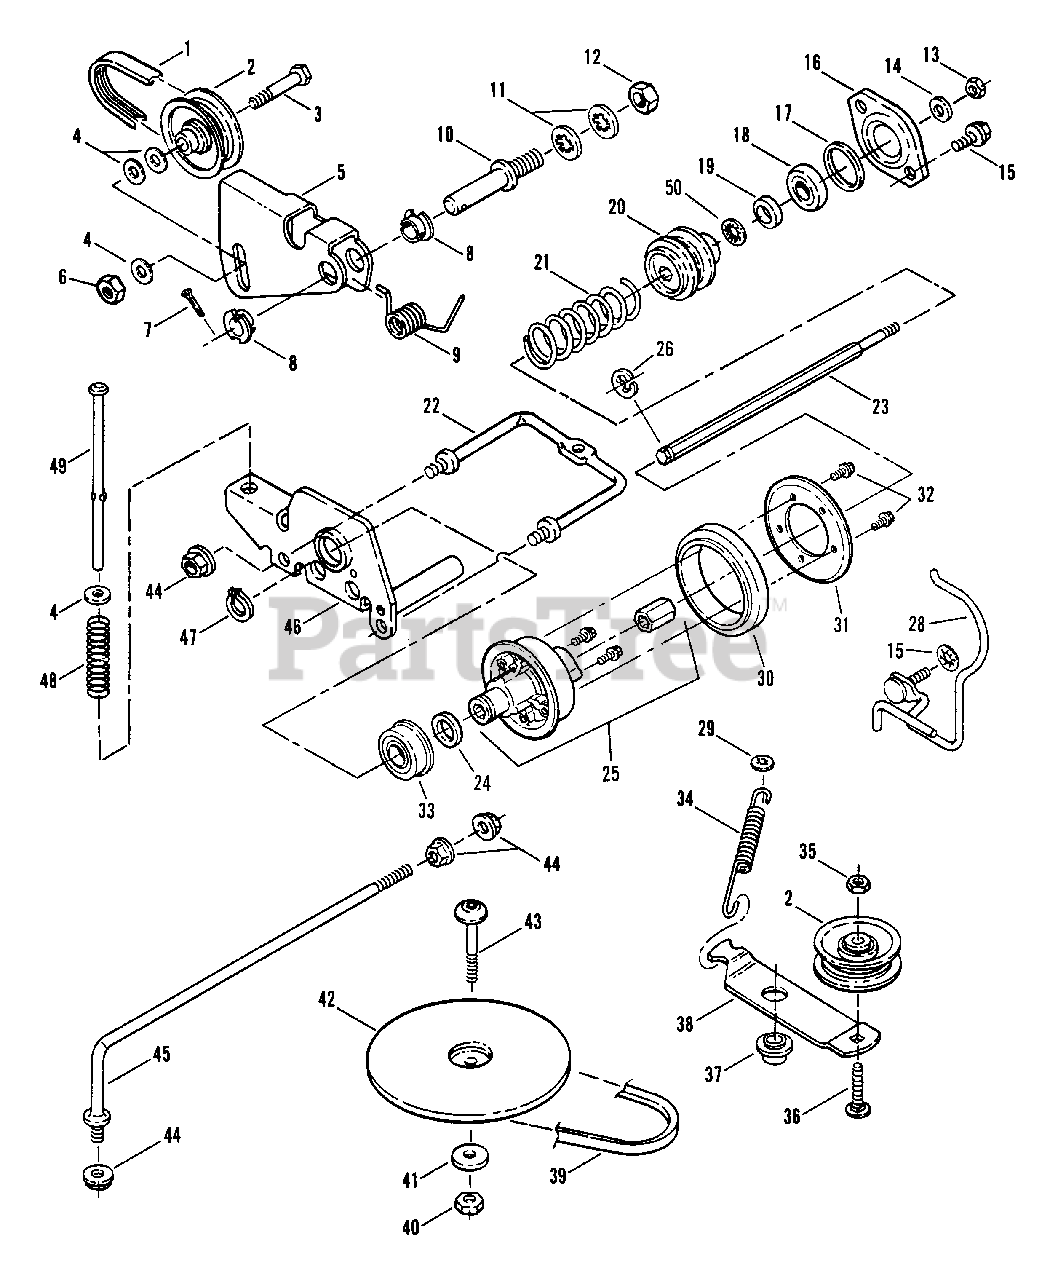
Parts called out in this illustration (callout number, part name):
1	BELT, Poly-V
2	PULLEY, Idler
3	SCREW, 1/4-28 x 1-3/8" Hex Head Cap
4	WASHER, 1/4 Flat
5	ARM, Idler
6	NUT, 1/4-20 Hex Top-Lock
7	PIN, 3/32 x 1/2" Cotter
8	BUSHING, Idler Arm
9	SPRING, Idler Arm
10	STUD, 3/8 x 2-1/8"
11	WASHER, 3/8 Internal Tooth Lock
12	NUT, 3/8-24 Hex
13	NUT, 3/8-24 Hex Center Lock
14	WASHER, Flat
15	SCREW, 1/4-20 x 5/8" Self-Tapping
16	RETAINER, Bearing
17	O-RING
18	BEARING
19	SPACER
20	PULLEY
21	SPRING, Return
22	GUIDE
23	SHAFT, Hex Drive
24	WASHER, Shim
25	ASSEMBLY, Hub (Includes 11108 Bushing & 90913 Screws)
26	RING, Retaining
28	GUIDE, Belt (Front)
29	RETAINER, 5/16 Bolt
30	RING, Driven
31	PLATE, Pivot
32	SCREW, #10-24 x 1/2" Hex Washer Self-Tap (Torx)
33	BEARING
34	SPRING, Idler Arm
35	NUT, 1/4-20 Hex Jam
36	BOLT, 1/4-20 x 1-1/8" Flat Head Carriage
37	SPACER, Idler Arm
38	ARM, Idler
39	BELT, Engine Drive
40	NUT, 7/16-14 Hex Lock
41	WASHER, Flat
42	ASSEMBLY, Drive Disc
43	SCREW, 7/16-14 x 2" Truss Head (Torx)
44	NUT, 5/16-18 Hex Flange Lock
45	ROD, Guide
46	ASSEMBLY, Thrust Plate
47	RING, Retaining
48	SPRING, Plunger Rod
49	ROD, Plunger
50	RETAINER, 5/16 Bolt
